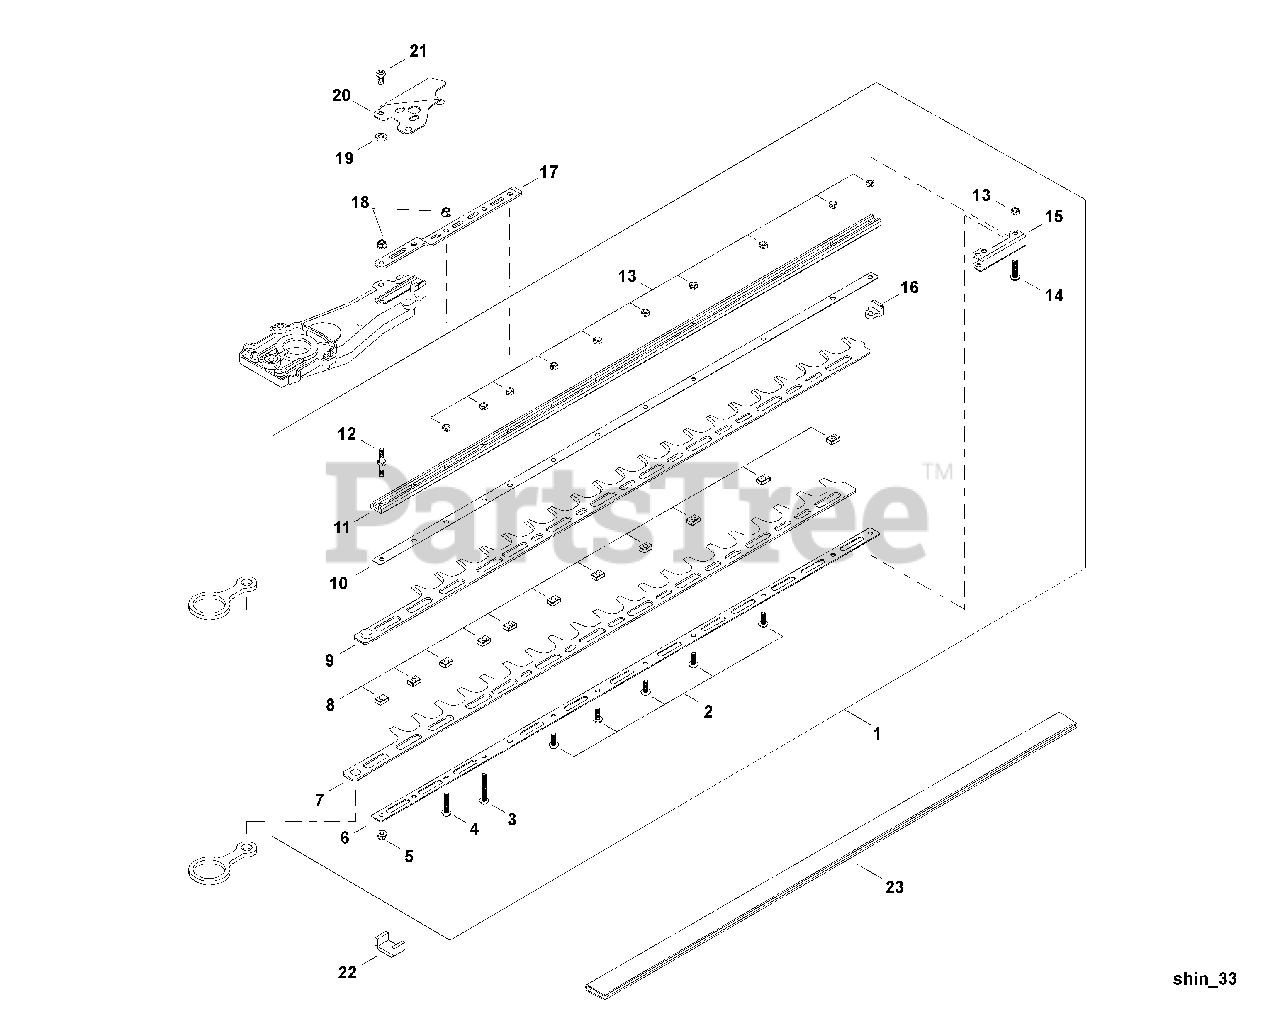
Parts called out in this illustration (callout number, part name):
1	BLADE KIT - 30" (76cm)
2	SCREW - 5X14
3	SCREW - 5
4	SCREW - 5X25
5	NUT - 5
6	PLATE - LOWER
7	BLADE - 30" (76mm) -- UPPER
9	BLADE - 30" (76mm) -- UPPER
10	PLATE - UPPER -- 30" (76cm)
11	SUPPORT, BLADE - 30" (76cm)
13	LOCKNUT - 5
14	SCREW - 5X22
15	PLATE, GUIDE
16	GUIDE, BLADE
17	PLATE, ANGLE
18	NUT - 5
19	WASHER - 5
20	PROTECTOR
21	SCREW - 6X12
22	SEAL, FELT
23	COVER, BLADE - 30" (76cm)
